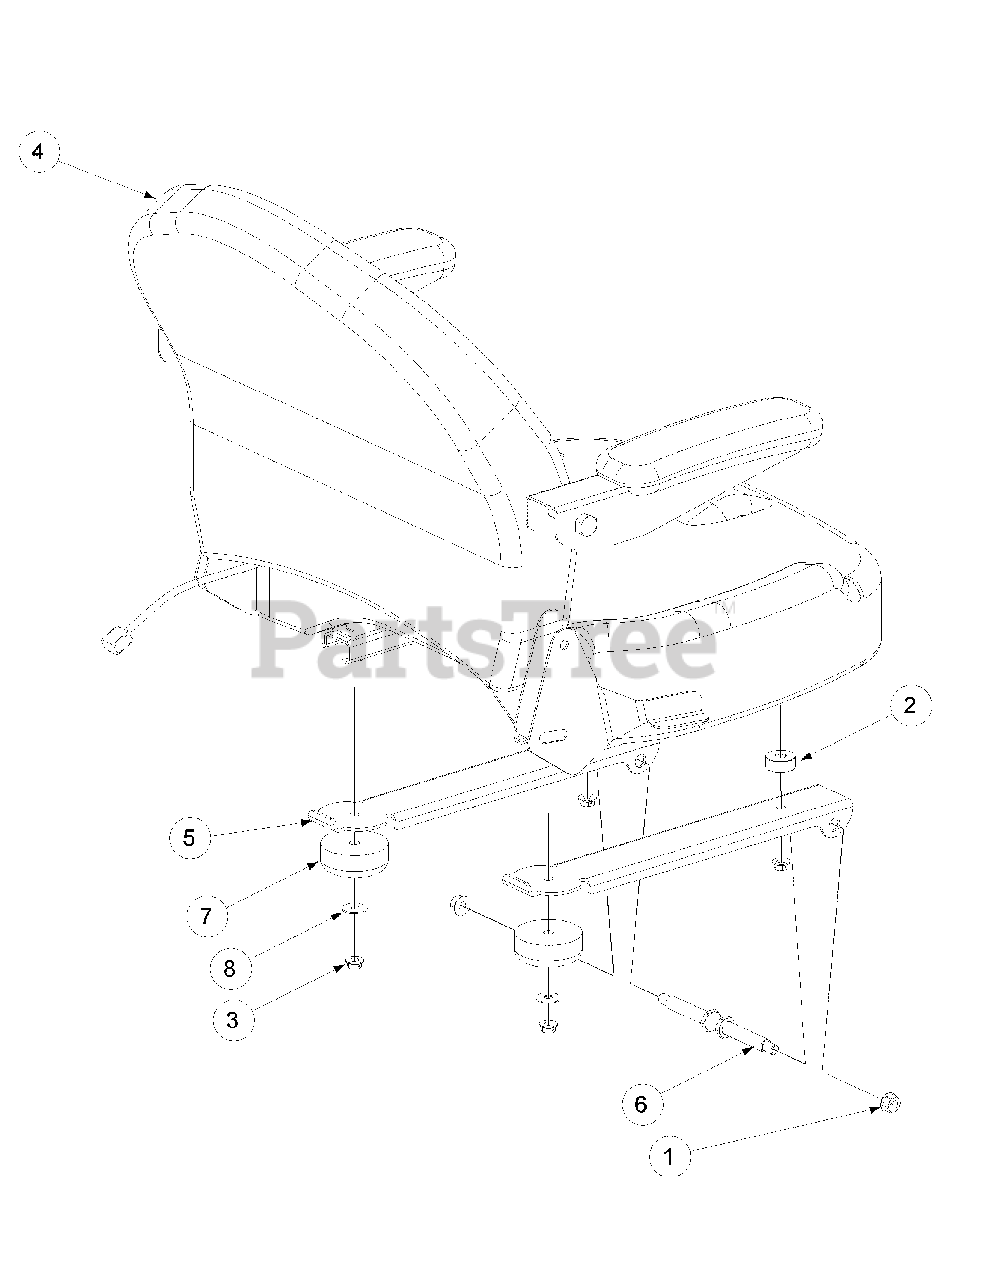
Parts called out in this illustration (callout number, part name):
1	Nut, Hex 3/8-16 Flange Lock
2	Spacer, 0.345 ID x 1.50 OD x .41
3	Lock Nut, Hex Flange, 5/16-18
4	Adjustable Seat, Black embossed, Forward Fold
5	Mounting Bracket, Seat w/ Stop
6	Shoulder Screw, .50x2.345, 3/8-16
7	Grommet, 2.5 OD x 1.0 Long
8	Washer
